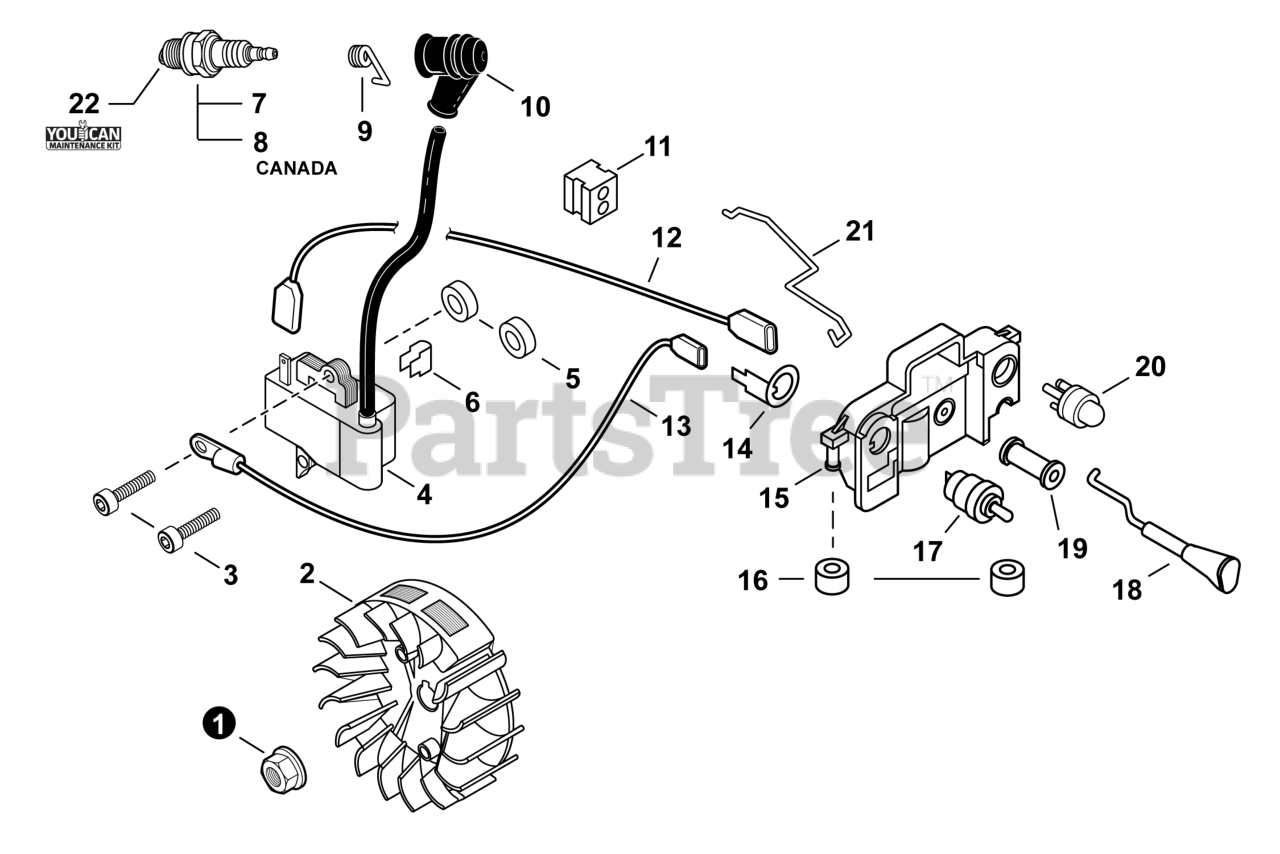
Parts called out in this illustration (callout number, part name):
1	NUT, FLANGE M8
2	FLYWHEEL
3	BOLT 5×20
4	COIL, IGNITION
5	WASHER 5.2×12×3
7	SPARK PLUG - BPM8Y
8	SPARK PLUG - BPMR8Y
9	TERMINAL, SPARK PLUG
10	CAP, SPARK PLUG
11	GROMMET, LEAD
12	LEAD - IGNITION L= 172
13	LEAD - GROUND L= 140
14	TERMINAL, GROUND
15	BRACKET, SWITCH
17	SWITCH, ON-OFF
18	KNOB, CHOKE
19	GROMMET, CHOKE
20	BULB, PURGE
21	ROD, THROTTLE
22	TUNE-UP KIT - YOUCANT
